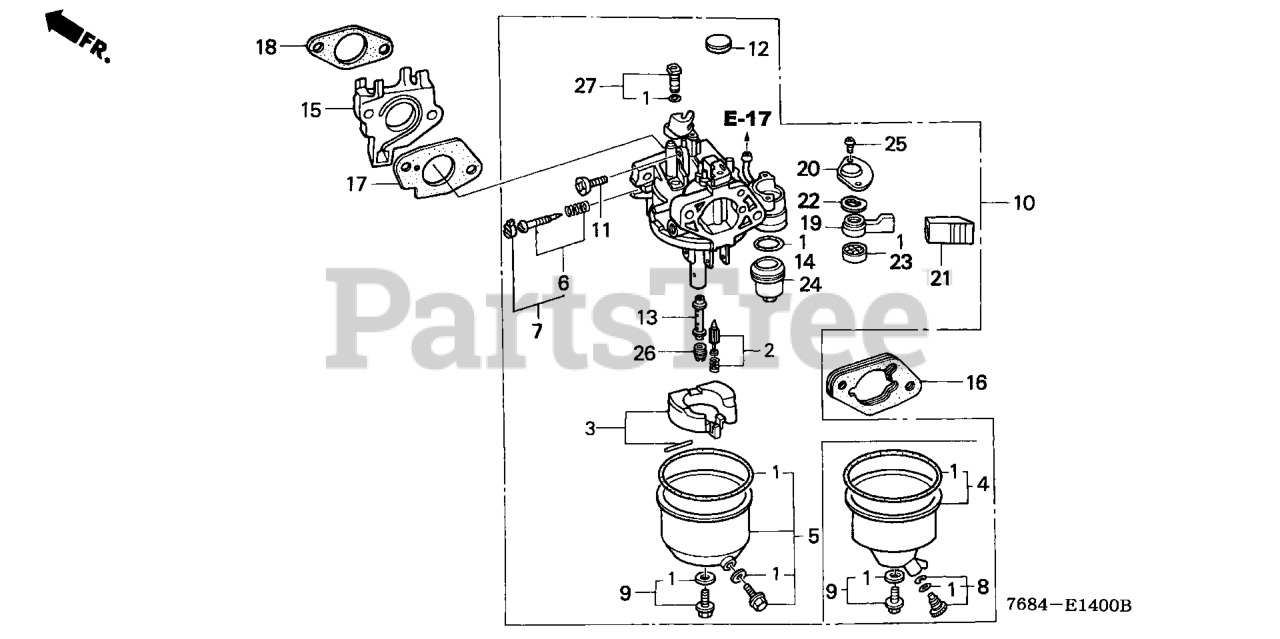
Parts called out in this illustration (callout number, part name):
1	GASKET SET (CARBURETOR NO.)
2	VALVE SET, FLOAT
3	FLOAT SET
4	CHAMBER SET, FLOAT (CARBURETOR NO.)
6	SCREW SET, PILOT (Honda Code 1441500). (CARBURETOR NO.)
8	SCREW SET, DRAIN (CARBURETOR NO.)
9	SCREW SET B
9	SCREW SET
10	CARBURETOR ASSY. (BE17B C)
11	SCREW, THROTTLE STOP
12	CAP, CHOKE LEVER DUST
13	NOZZLE, MAIN
14	GASKET, FUEL STRAINER CUP
15	INSULATOR, CARBURETOR
16	SPACER, CARBURETOR
17	GASKET, CARBURETOR
18	GASKET, INSULATOR
19	LEVER, VALVE
20	PLATE, LEVER SETTING (CARBURETOR NO.)
21	CAP, LEVER
22	SPRING, PETCOCK LEVER (CARBURETOR NO.)
23	GASKET, VALVE
24	CUP, FUEL STRAINER
25	SCREW, PAN (3X8) (CARBURETOR NO.)
25	SCREW, PAN (3X6)
26	JET, MAIN (#92) Use up to Engine SN BE37B A.
26	JET, MAIN (#88) Use up to Engine SN BE81B B.
26	JET, MAIN (#90) Use from Engine SN BE81B C.
27	JET SET, PILOT (#38)
